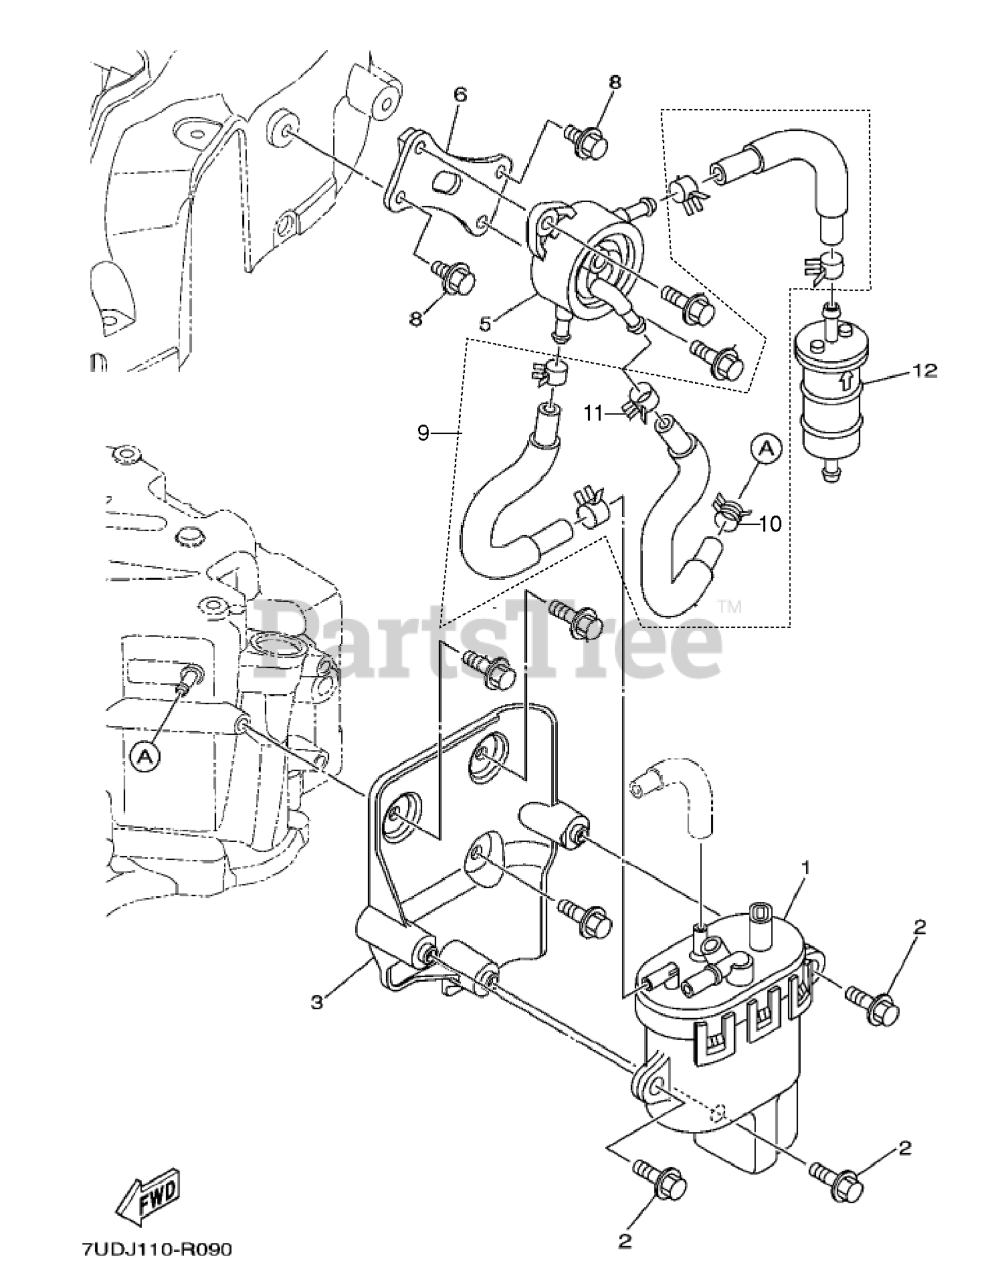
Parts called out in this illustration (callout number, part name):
1	FUEL PUMP COMP YAMAHA PN: 7UD-
2	BOLT YAMAHA PN: 95822-06016
3	BRACKET FUEL PUMP 1 YAMAHA PN:
5	FUEL PUMP ASSY YAMAHA PN: 7VV-
6	BRACKET FUEL PUMP 2 YAMAHA PN:
8	BOLT YAMAHA PN: 95822-06010
9	HOSE KIT FUEL PUMP
10	CLIP SERVICE KIT X10
11	CLIP SERVICE KIT X10
12	FUEL FILTER YAMAHA PN: 7UD-F4
